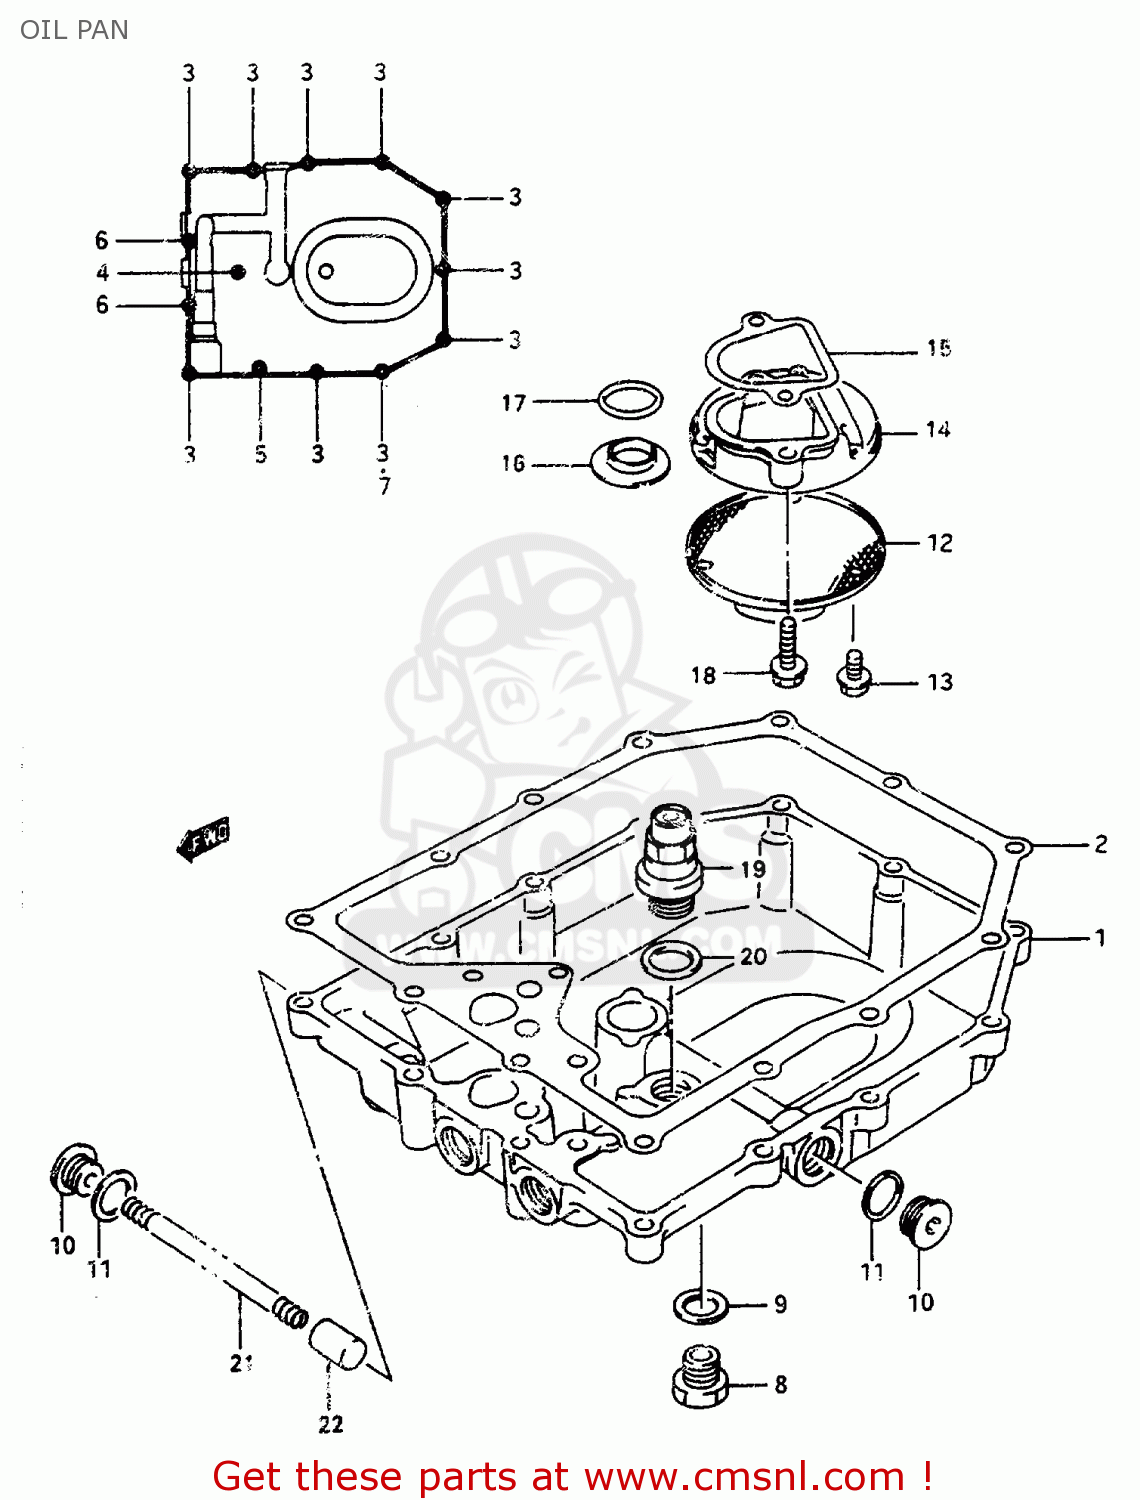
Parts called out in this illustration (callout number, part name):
1	PAN,OIL
2	GASKET,OIL PAN (NAS)
3	BOLT,CL.COVER
4	BOLT
5	BOLT
6	BOLT
7	GASKET(5.8X11X1.2) (NAS)
8	PLUG
9	GASKET(13.8X18.8X4.8) (NAS)
10	PLUG
11	GASKET(16X22X2) (NAS)
12	STRAINER,ENGINE OIL
13	BOLT
14	PROTECTOR,OIL STRAINER
15	GASKET,OIL STRAINER PROTECTOR (NAS)
16	GASKET,OIL OUTLET (NAS)
17	O RING(D:3.2,ID:17.8)
18	BOLT
19	VALVE ASSY,OIL RELIEF
20	GASKET(16X22X2) (NAS)
21	SPRING
22	PLUNGER,OIL CONTROLL
